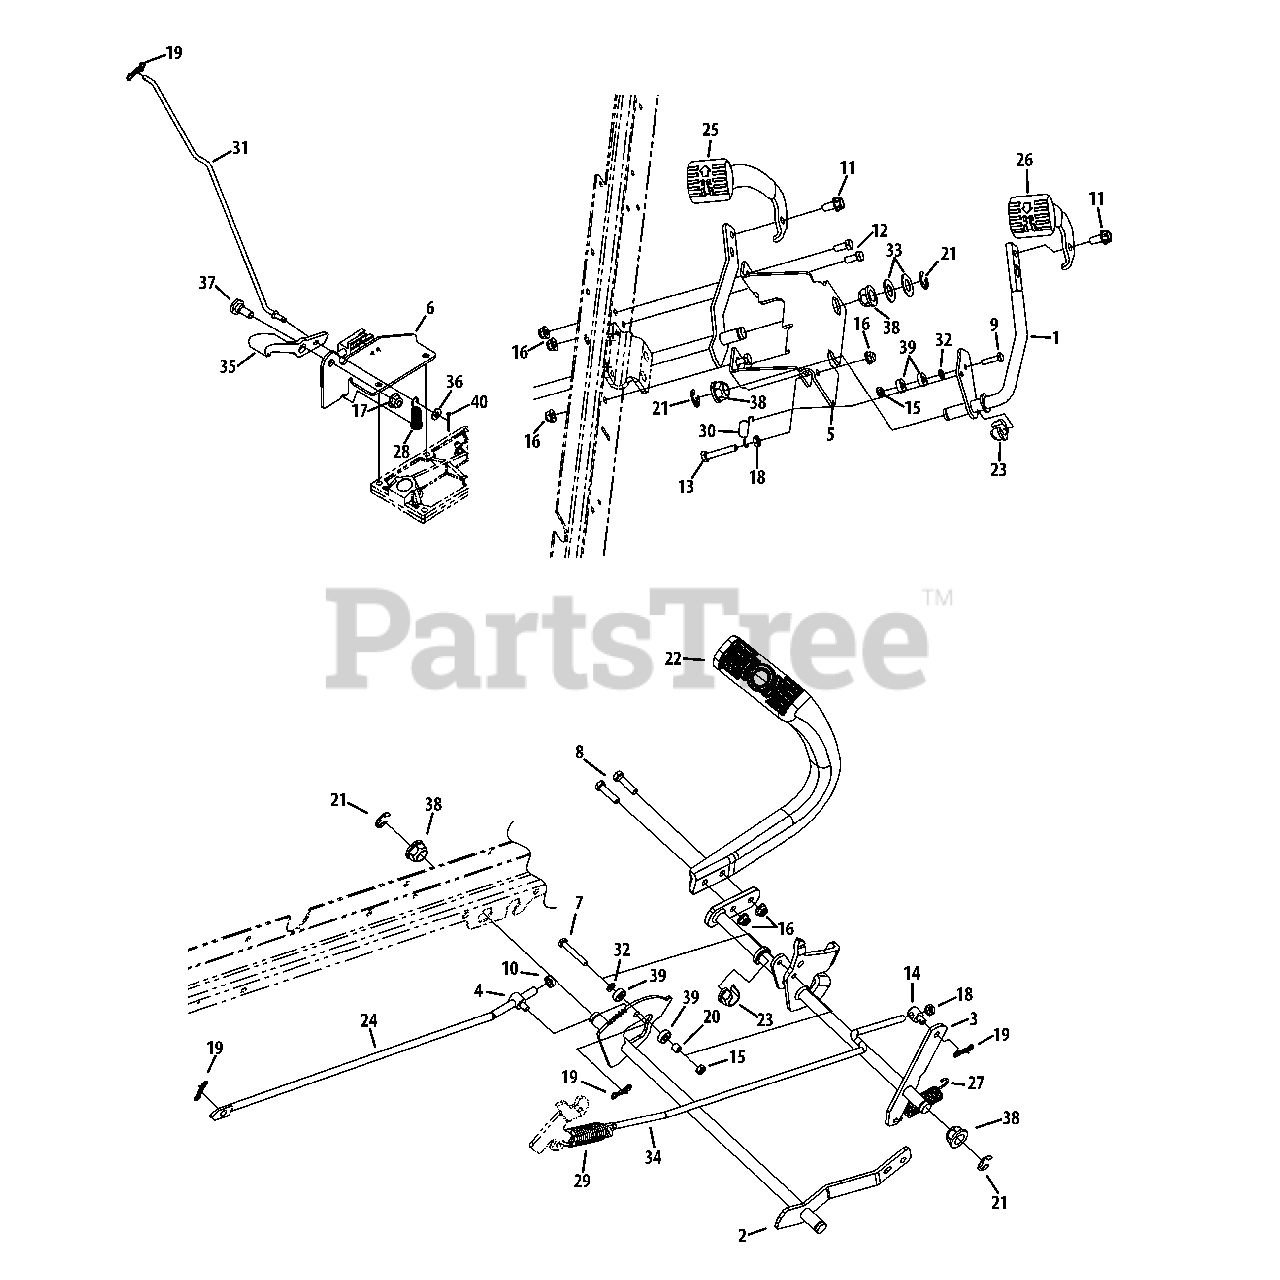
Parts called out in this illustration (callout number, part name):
1	Reverse Shaft Assembly
2	Forward Shaft Assembly
3	Brake Shaft Assembly
4	Ferrule, 3/8-16 x .312
5	Pedal Bracket
6	Cruise Pedal Mount Bracket
7	Hex Screw, 1/4-20 x 1.75
8	Hex Screw, 5/16-18 x 1.25
9	Hex Screw, 1/4-20 x 1.00
10	Jam Nut, 3/8-16
11	Hex Washer Screw, 3/8-16 x .750
12	Hex Screw, 5/16-18 x .75
13	Hex Screw, 5/16-18 x 1.75
14	Ferrule, 5/16-18 x .312
15	Hex Lock Nut, 1/4-20
16	Flange Lock Nut, 5/16-18
17	Flange Lock Nut, 3/8-16
18	Jam Nut, 5/16-18
19	Bow-Tie Cotter Pin, 72
20	Spacer, .375 x .25 x .335
21	E-Ring, .625
22	Pedal Bracket
23	Hex Flange Bearing, .628
24	Hydro Control Rod
25	Forward Pedal
26	Reverse Pedal
27	Extension Spring, .770 x 3.720
28	Cruise Extension Spring
29	Extension Spring, .95 x 4.00
30	Extension Spring, .51 x 2.12
31	Latch Control Rod
32	Flat Washer, .281 x .50 x .063
33	Flat Washer, .64 x 1.24 x .06
35	Cruise Latch
36	Flat Washer, .271 x .630 x .065
37	Shoulder Screw, 3/8-16 x .50 x .27
38	Hex Flange Bearing
39	Ball Bearing, .25 x .6875 x .25
40	Cotter Pin 3/32" Dia. x 1" Lg.
